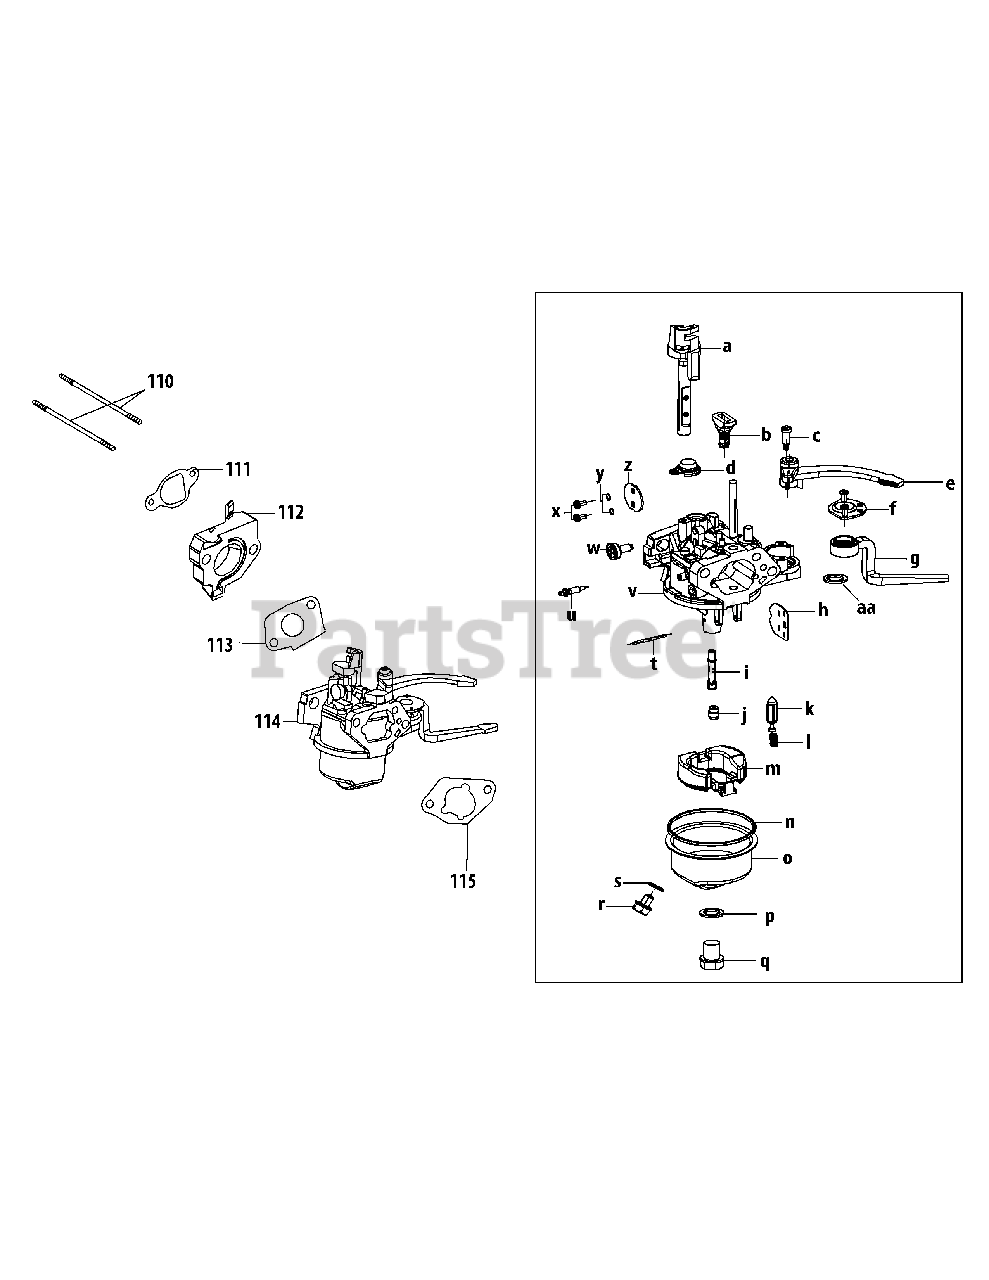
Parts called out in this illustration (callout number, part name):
110	Carburetor Stud
111	Carburetor Insulator Gasket
112	Carburetor Insulator
113	Carburetor Gasket
114	Carburetor Assembly
115	Carburetor Gasket Plate
